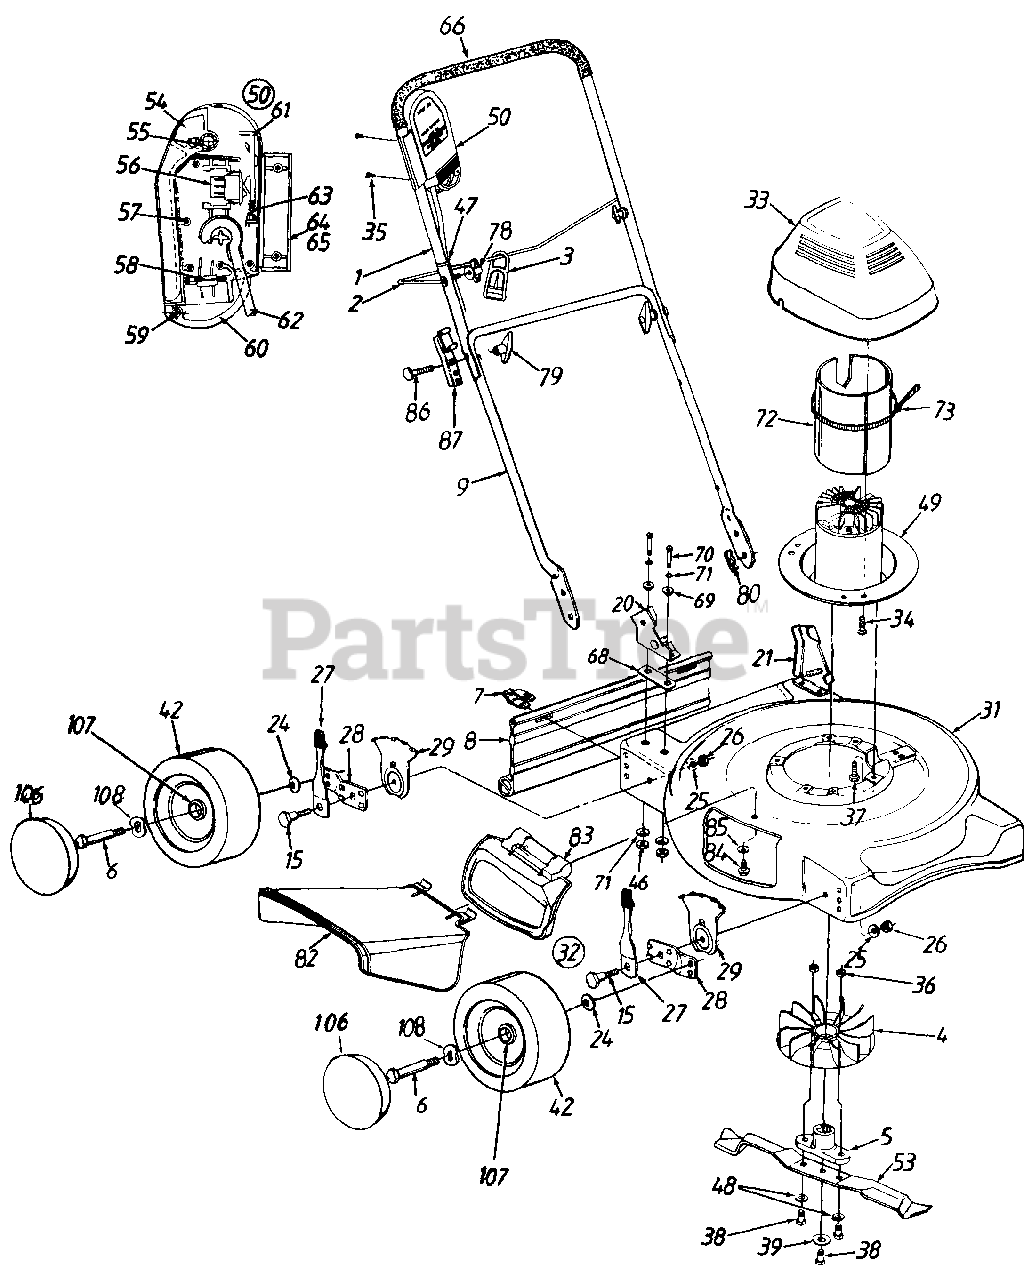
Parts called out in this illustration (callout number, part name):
1	Upper Handle
2	Cord Control Rod
3	Strain Relief - Cord
5	Blade Adapter
6	Axle Bolt
7	Hinge Clip
8	Rear Flap
15	Shld. Bolt .5" Dia. x .434"
20	Handle Brkt. Ass'y. - R.H.
21	Handle Brkt. Ass'y. - L.H.
24	Bell-Wash .38" I.D. x .88" O.D.
25	Bell-Wash .39" I.D. x 1.38" O.D.
26	Hex Nut 3/8-16 Thd.
27	Spring Lever Ass'y. w/Knob
29	Height Adj. Plate
31	20" Deck Ass'y.
32	Height Adj. Ass'y. Comp.- R.F. & L.R.
33	Motor Cover (Yellow)
34	Scr. #10-16 x .75" Lg.
35	Self-Tap Scr. #7 x 1" Lg.
36	Hex Nut 3/8-24 Thd.
37	Hex L-Wash. TT-Tap Scr. 3/8-16 x .75" Lg.
38	Hex Bolt 3/8-24 x 1.25" Lg.
39	Bell-Wash.396" I.D. x 1.14" 0.D.
42	Wheel Ass'y. Comp. (Gray Rim)
46	Hex Top L-Nut 1/4-20 Thd.
47	Cable Tie
48	L-Wash. 3/8" I.D.
49	Motor, Cord & Switch Ass'y.
50	Cord & Switch Ass'y. Comp.
53	20" Mulching Blade
54	Handle - Switch Actuator
55	Spring - Switch Handle
56	Switch
57	Screw #6-32 x .5" Lg.
58	Plug Ass'y.
59	Retainer Plug Spring
60	Retainer Plug
61	Latch
62	Cord Ass'y.
63	Spring Latch
64	Housing - Upper Half
66	Foam Grip
68	Insulator Strip
69	Insulator Shield
70	Hex Bolt 1/4-20 x 1" Lg.
71	Fl-Wash .26" I.D. x .72" O.D.
72	Insulator
73	Cable Tie
78	Wing Nut
79	Wing Nut Ass'y.
80	Hairpin Clip
82	Chute Deflector
83	Mulching Plug Ass'y.
84	Hex Wash. Hd. TT-Tap Scr. 1/4-20 x .5" Lg.
85	Bell-Wash. 1/4" I.D.
86	Carr. Bolt 5/16-18 x 2" Lg.
87	Handle Bracket
106	Hub Cap
107	Ball Bearing
108	Wave Wash.
